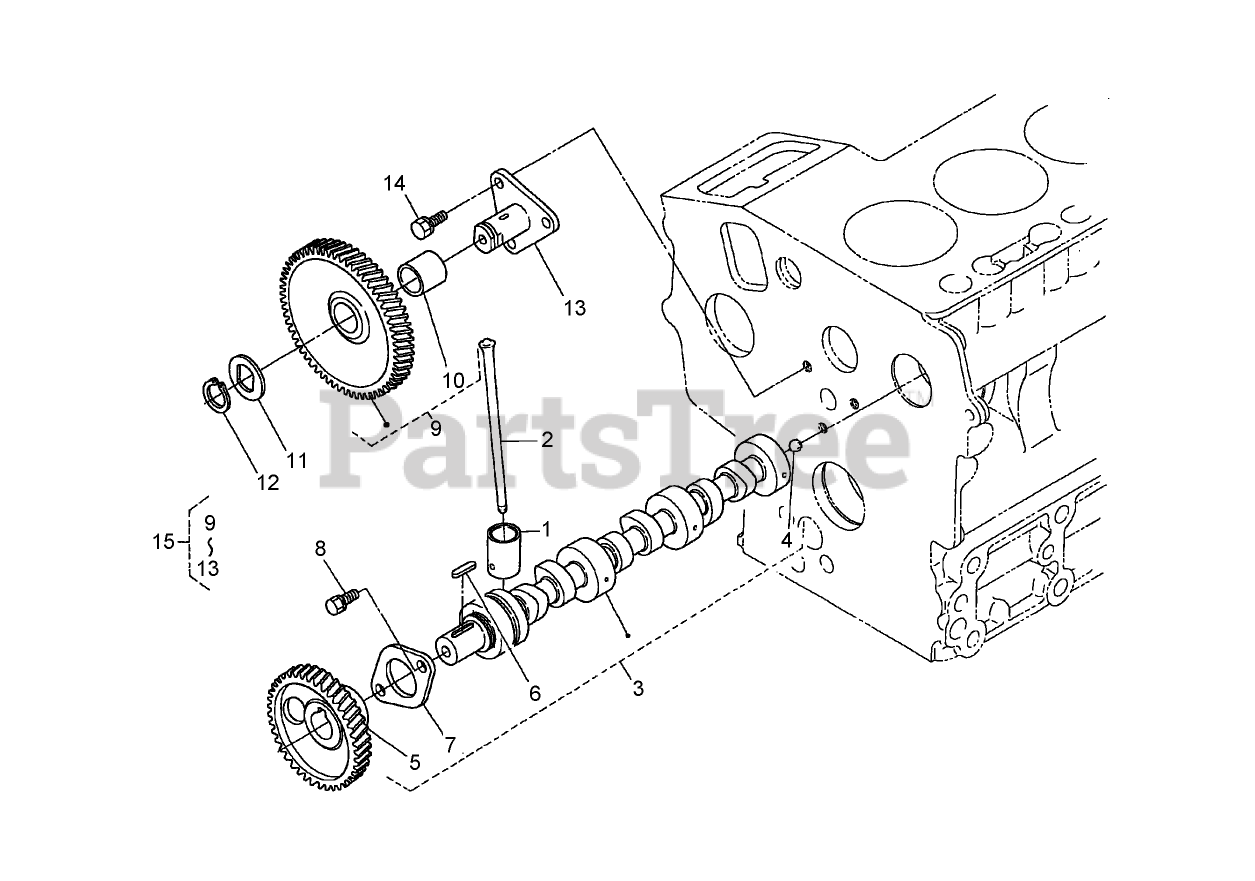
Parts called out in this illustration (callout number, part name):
1	TAPPET
2	ROD-PUSH
3	CAMSHAFT ASM
5	GEAR-CAM
6	KEY-FEATHER
7	STOPPER-CAMSHAFT
9	GEAR-IDLE
10	BUSHING
11	COLLAR-GEAR, IDLE
12	RING-SNAP
13	SHAFT-GEAR, IDLE
15	IDLE GEAR ASM
